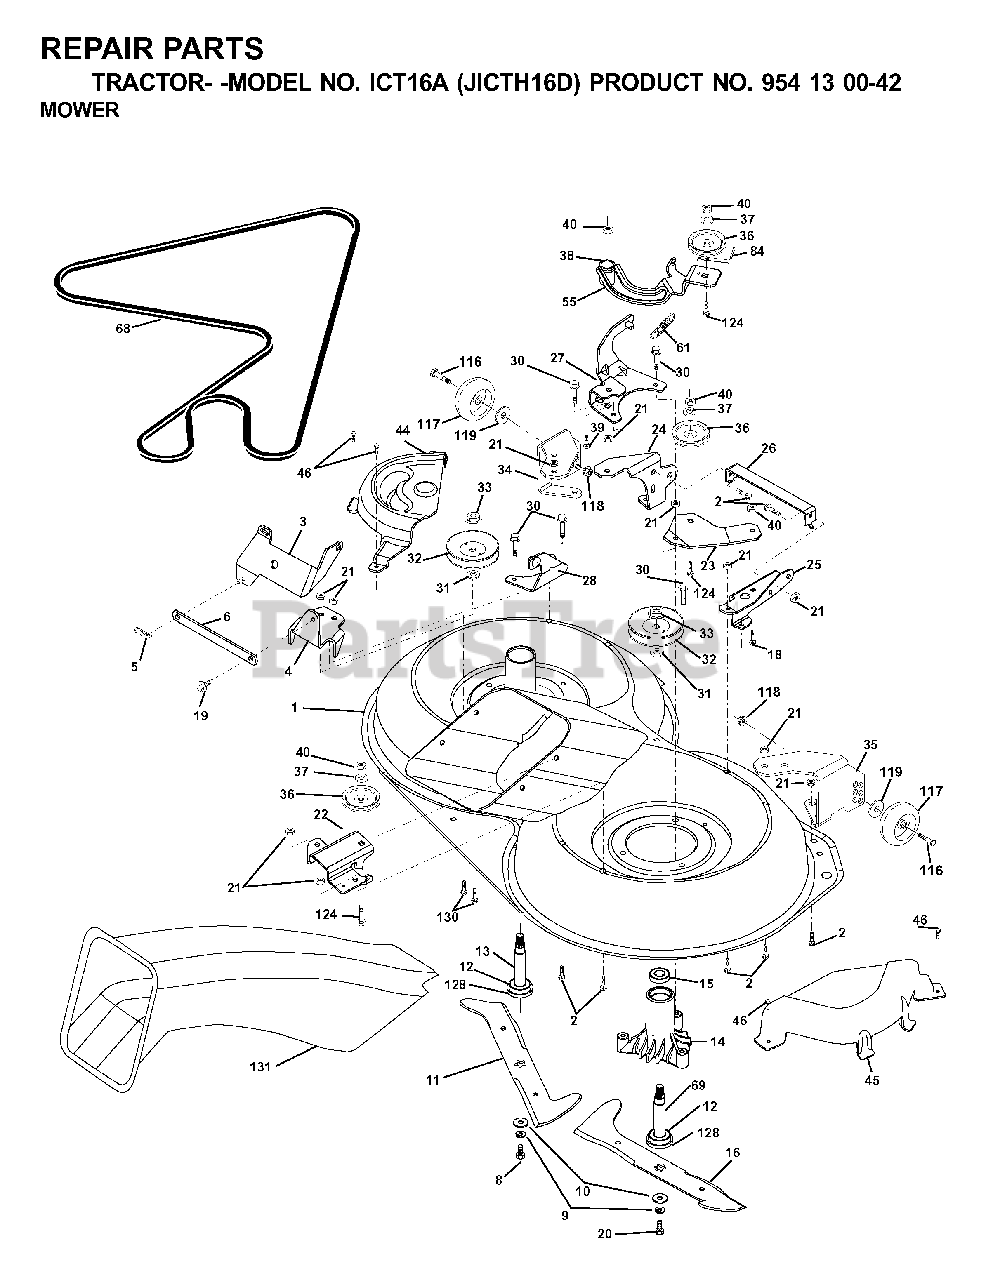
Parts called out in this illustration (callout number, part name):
2	BOLT
3	BRACKET
5	RETAINER-SPRNG RB
6	BAR SWAY
8	BLADE BOLT
9	LOCKWASHER
10	WASHER.BLADE
11	BLADE - LH (CTH150)
12	BEARING
13	SHAFT ASM VENT
14	HSG MANDREL
16	BLADE - RH (CTH150)
19	BOLT SHD 5/16-18
21	LOCKNUT
22	BRACKET
23	BRACKET
26	BRACE
27	BRACKET
30	SCREW THDROL ROLLING WASHER HD
31	WASHER
32	PULLEY/MANDREL
33	NUT
34	BRACKET
36	PULLEY.IDLER.4.25
40	LOCKNUT
45	MANDREL COVER RH
46	SCREW.1/4-20X5/8
55	ARM IDLER
61	SPRING.TENSION.BELT
68	HEX-BELT 107 MOWER
69	SHAFT.ASM.W/LWR.BRG.RH.THREAD
84	KEEPER, BELT IDLER
116	BOLT, SHOULDER
117	WHEEL GAGE DONUT
118	LOCKNUT
119	WASHER
124	BOLT.3/8-16X1.50
128	WASHER FELT
131	CHUTE BAGGER
